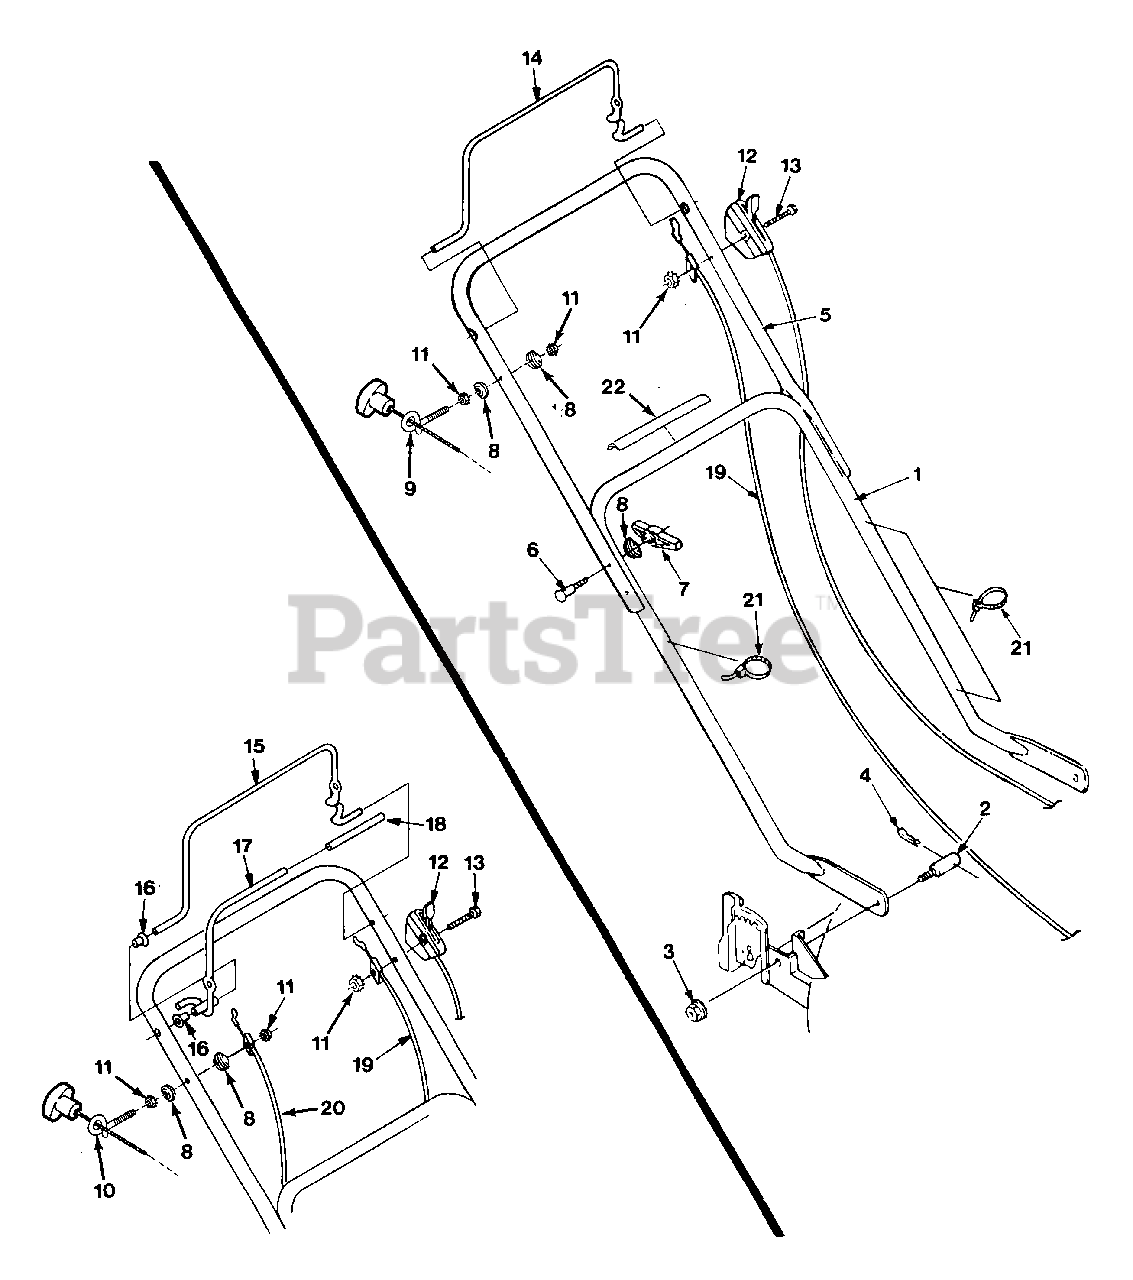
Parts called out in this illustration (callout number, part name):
1	Handle - lower
2	Stud - handle mounting
3	Nut - hex 5/16-18 finge lock
5	Handle - upper
6	Bolt - Curved head
7	Knob - handle, plastic
8	Washer - curved
9	Eyebolt - starter rope, short
10	Eyebolt - starter rope, long
11	Nut - hex 1/4-20 Keps
12	Control - throttle w/cable
13	Bolt - hex 1/4-20 x 2-1/4
14	Bail - engine/blade control
15	Bail - engine/blade control
16	Bushing - control bail
17	Bail - ground drive control
18	Sleeve - ground drive bail
19	Cable - engine/blade control
20	Cable - ground drive
21	Cable Tie
22	Decal - starting instructions
